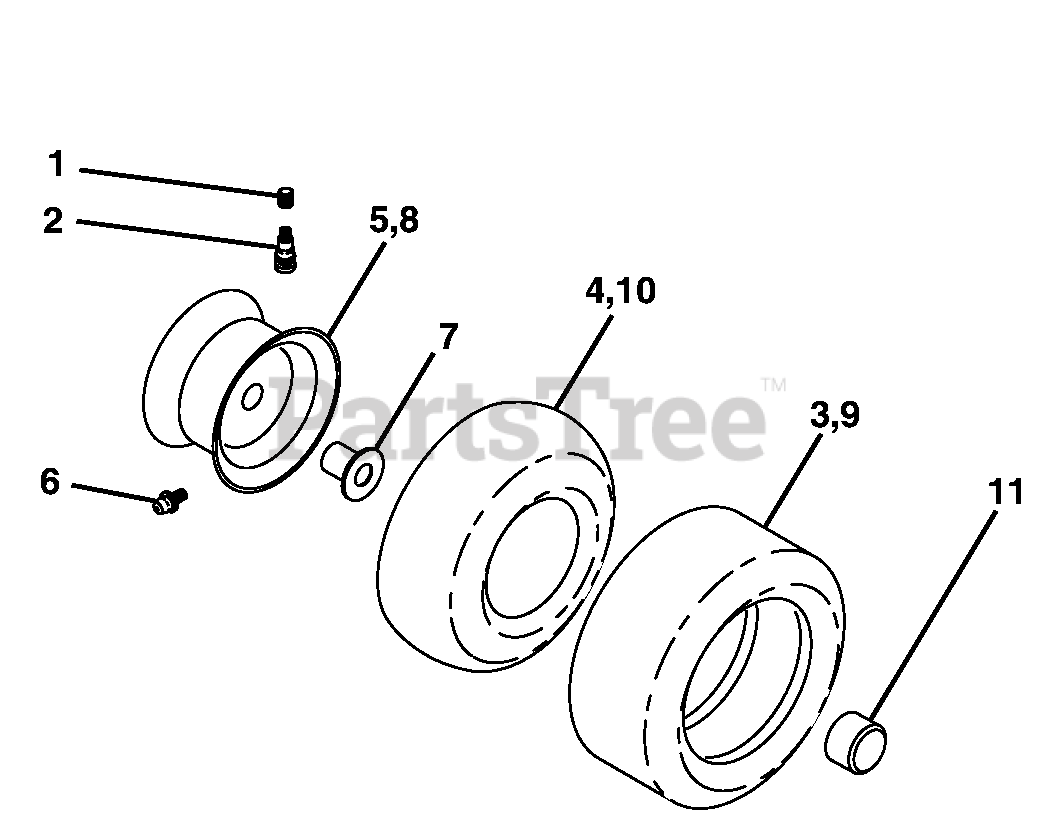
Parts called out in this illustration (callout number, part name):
1	Cap Valve Tire
2	Stem Valve
3	Tire F T 15 x 6 0 - 6 Service
4	Tube Front (Service Item Only)
5	Rim Asm 6"front Service
6	Fitting Grease (Front Wheel Only)
7	Bearing Flange (Front Wheel Only)
8	Rim Asm 8"rear Service
9	Tire R T 20 x 8-8 C Service
10	Tube Rear (Service Item Only)
11	Cap Axle 1 50 x 1 00
